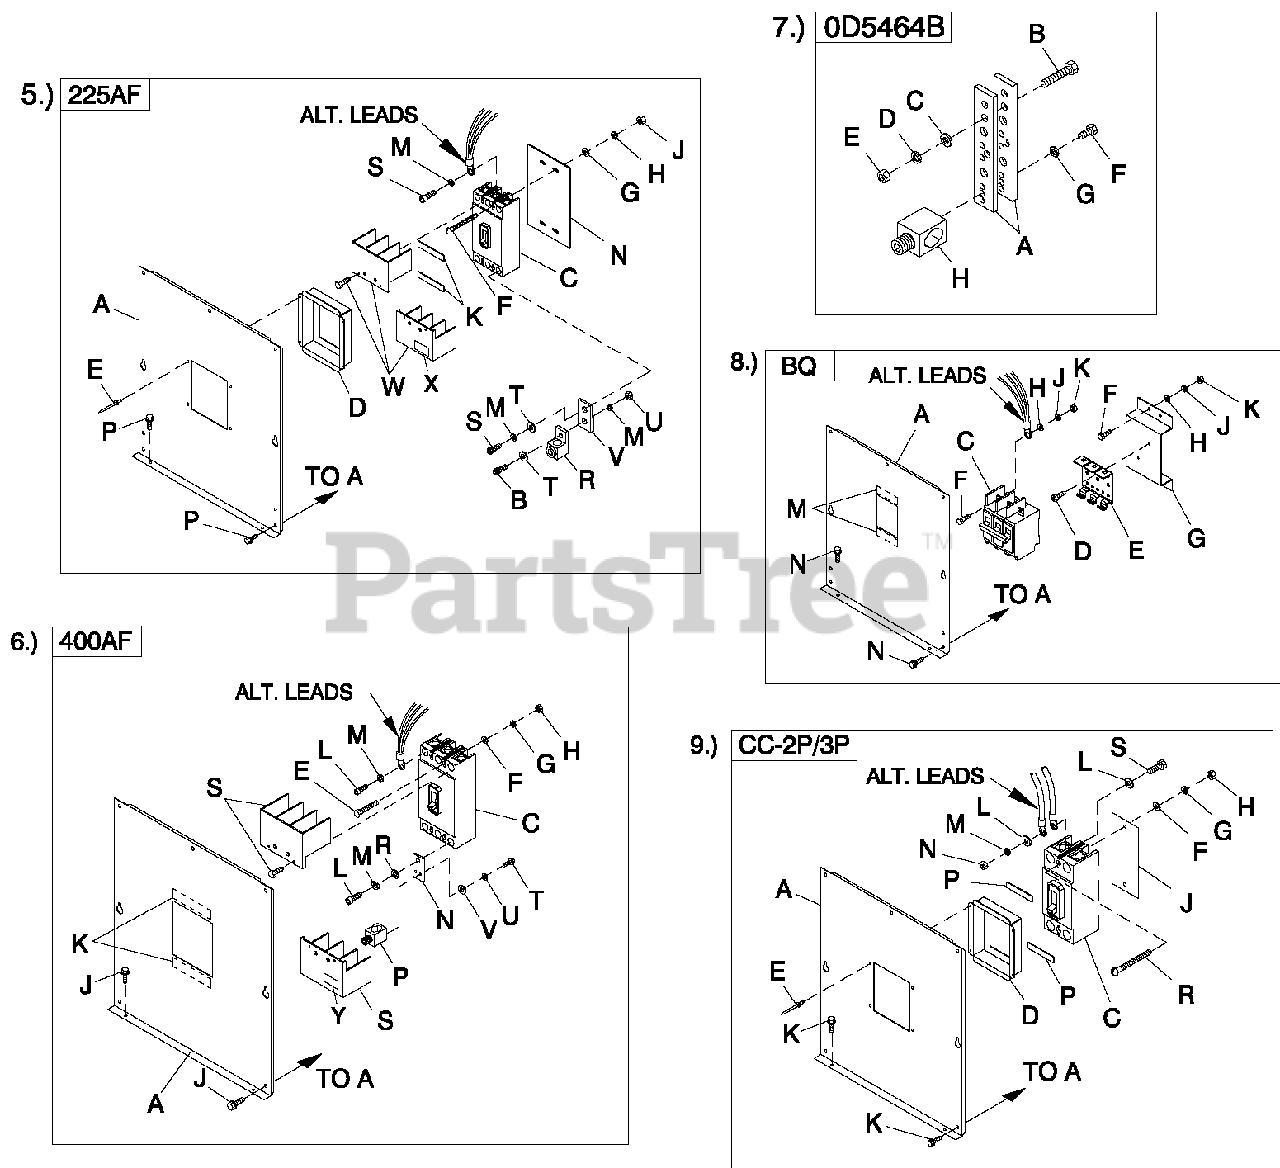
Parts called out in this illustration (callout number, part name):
8	UL CIRCUIT BREAKER (BQ)
A	COVER CBC2-C4(225AF)
B	SCREW SHC M8-1.25 X 25 G12.9
C	CIRCUIT BREAKERS 200A FRAME (3P)
D	COVER CB DISH 225AF (3P)
E	RIVET POP .125 X . 275 SS
F	SCREW RHM #8-32X3-1/4
G	WASHER FLAT #8 ZINC
H	WASHER LOCK #8-M4
J	NUT HEX #8-32 STEEL
K	TAPE ELEC 1/2 FOAM
M	WASHER LOCK M8-5/16
N	INSULATOR CB225AF (3P)
P	SCREW THF M6-1 X 16 N WA Z/JS
R	LUG SLDLSS 300 MCM-6 AL/CU
S	SCREW SHC M8-1.25X20G8
T	WASHER FLAT 5/16-M8 ZINC
U	NUT HEX M8-1.25 G8 CLEARZINC
V	BUS BAR 200A LUG ADAPTOR
W	TERMINAL COVER CB
X	DECAL TERMINAL SHOCK HZD BI
A	COVER CBC2-C4 400AF
C	CIRCUIT BREAKERS 400A FRAME
E	SCREW RHM 10-32X4
F	WASHER FLAT #10 ZINC
G	WASHER LOCK #10
H	NUT HEX #10-32 STEEL
J	SCREW THF M6-1 X 16 N WA Z/JS
L	SCREW SHC M10-1.5X 25 G12.9
M	WASHER LOCK M10
N	BUS BAR CB ADAPTER 225-400 A
P	LUG SLDLSS 600/250-1/0 X 1/4-28
S	TERM COVER CB
T	SCREW HHC 1/4-28 X 1/2 G5
U	WASHER LOCK M6-1/4
V	WASHER FLAT 1/4-M6 ZINC
W	SCREW SHC M10-1.5X 25 G12.9
X	WASHER LOCK M10
Y	DECAL TERMINAL SHOCK HZD BI
A	BUS BAR NEUTRAL BLOCK 390
B	SCREW HHC M8-1.25 X 45 G8.8 FT
C	WASHER FLAT 5/16-M8 ZINC
D	WASHER LOCK M8-5/16
E	NUT HEX M8-1.25 G 8Y E L CHR
F	SCREW HHC 1/4-28 X 3/4 G5
G	WASHER LOCK 1/4-M6SS
H	LUG SLDLSS 600/250-1/0 X 1/4-28
A	COVER BQ CIR BREAKER CPL 3P
C	CB0125A2P 240V SBQ 2 LL
D	SCREW PHTT M4-0.7X 10 ZYC
E	BRKTCBMTG BACK
F	SCREW RHM #10-32X3/4
G	BRKT BQ C B STANDOFF
H	WASHER FLAT #10 ZINC
J	WASHER LOCK #10
K	NUT HEX #10-32 STEEL
M	TAPE ELEC 1/2 FOAM
N	SCREW THF M6-1 X 16 N WA Z/JS
C	CB 0175A 2P 240V EC CLL
D	COVER CB DISH 2P E CC
E	RIVET POP .125 X .275 SS
F	WASHER FLAT #8 ZINC
G	WASHER LOCK #8-M4
H	NUT HEX #8-32 STEEL
J	INSULATOR C B 2 P E TYPE CC
K	SCREW HWHT M6-1 X 16 N WAZ/JS
L	WASHER FLAT #10 ZINC
M	WASHER LOCK M5
N	NUT HEX M5-0.8 G8 CLEAR ZINC
P	TAPE ELEC 1/2 FOAM
R	SCREW RHM #8-32X3-1/4
S	SCREW HHC M5-0.8X 20 G8.8
